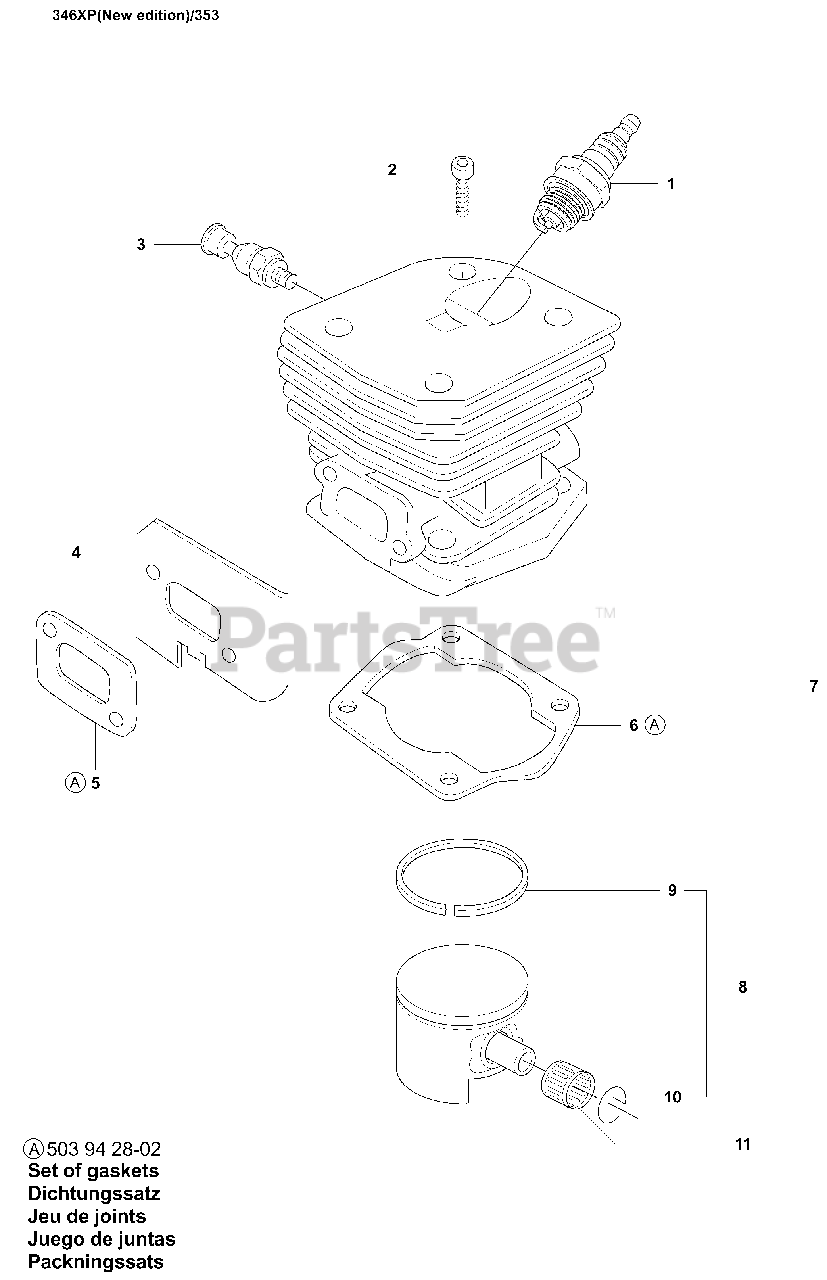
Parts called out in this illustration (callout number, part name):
1	SPARK PLUG RCJ7Y
2	SCREW MC6S 5X25
3	DECOMPRESSION VALVE
5	GASKET
6	GASKET
7	PISTON CYLINDER KIT 353
7	%CYLINDER
8	PISTON
8	%PISTON
8	PISTON ASSY
9	%PISTON RING
9	PISTON RING
10	LOCKING RING
11	SUPPORT BUSHING
A	GASKET SET
